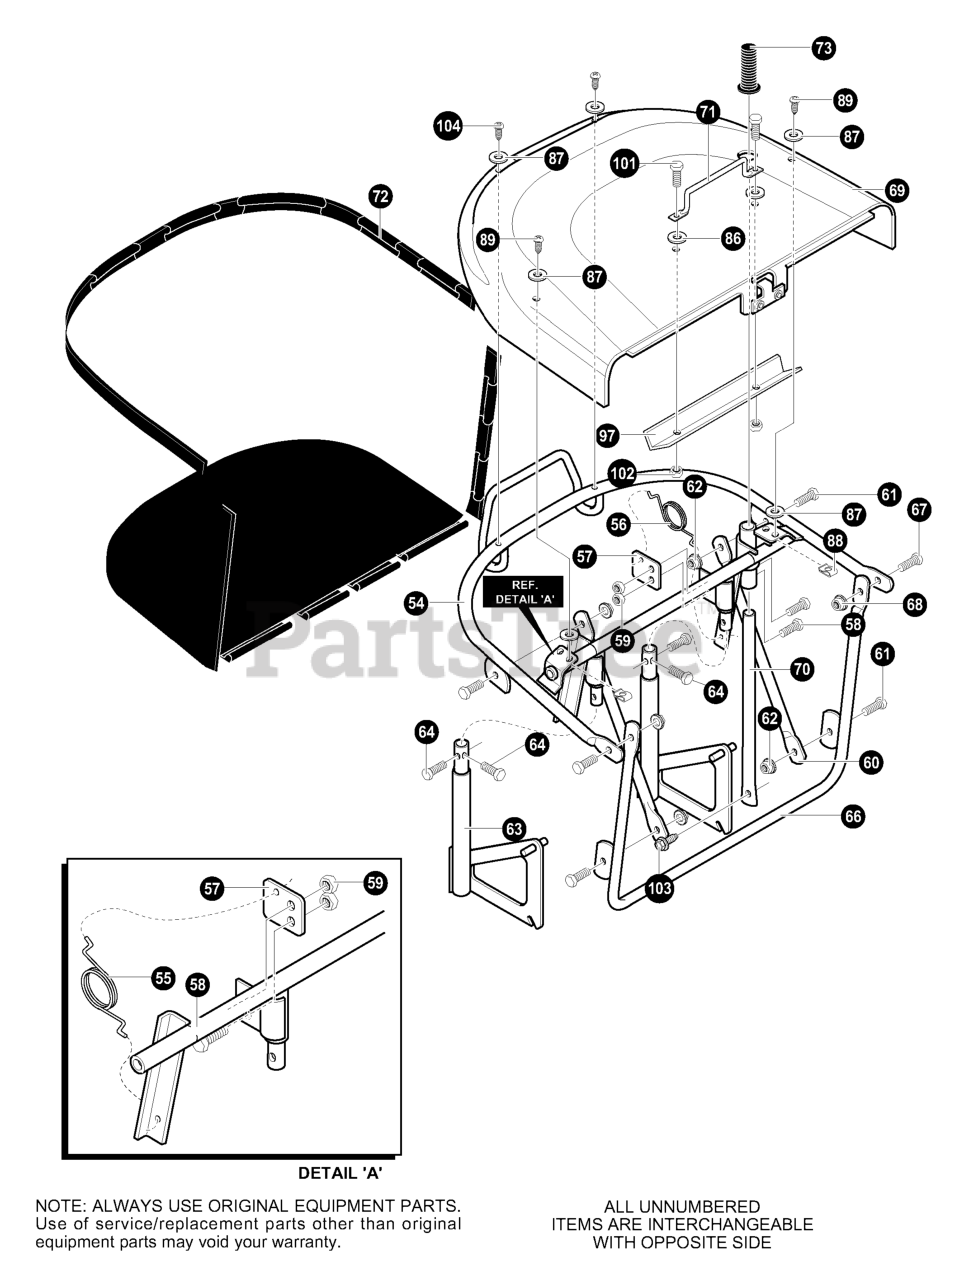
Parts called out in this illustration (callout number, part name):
54	ASM. WELD UPPER FRAME
55	SPRING, TORSION RH
56	SPRING, TORSION LH
57	BRACKET, SPRING COLLECTOR
58	SCREW, 1/4-20X.50 HHC
59	NUT, 1/4-20 REGHEXCTRLK
60	BRACE, FRAME COLLECTOR
61	SCREW, 1/4-20X.62 HHC
62	NUT, 1/4-20 HEXNYL
63	WELD ASM., SUPPORT COLLECTOR
64	SCREW, 1/4-20X1.50
66	WELD ASM., FRONT FRAME COLLECT.
67	SCREW, 1/4-20X.62 HHC
68	NUT, 1/4-20 HEXNYL
69	TOP COLLECTOR ASM.
70	HANDLE, DUMP COLLECTOR
71	HANDLE, REBA COLLECTOR
72	REBA COLLECTOR BAG
73	RUBBER GRIP
86	WASHER, .281X1.25X.06
87	WASHER, .328X1.06X.062
88	NUT, 1/4-20 TINN U
89	SCREW, 1/4-20X.63 PHPNHD
97	BRACE, BAGGER
101	SCREW 1/4-20X1.50 PHPNHD
102	NUT, 1/4-20 HEXNYL
103	SCREW, #12X.50 PHPNHTAP
104	SCREW, #12X.50 PHPNHTAP
